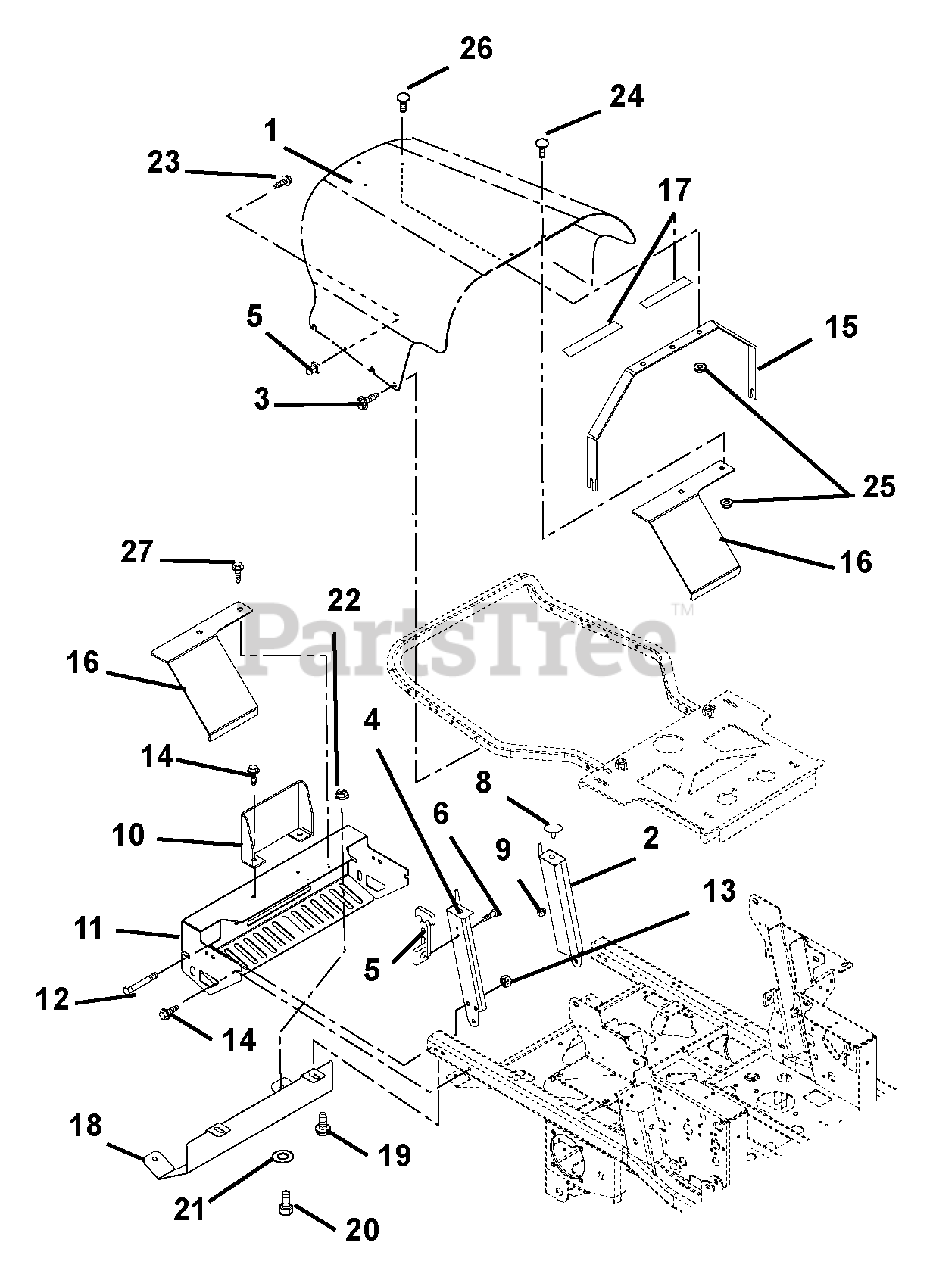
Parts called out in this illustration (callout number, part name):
1	Hood
2	Weldment, Hood Support, Left Hand
3	Screw, Tapping .38-16 x .50 Hex Washer Head
4	Weldment, Hood Support Right Hand
5	Latch, Rubber
6	Screw, Machine 10-24 x .50 Hex Washer Head
7	Screw, Machine 10-24 x 1.50 Hex Washer Head
8	Button Bumper
9	Nut-Spin Lock-Flange .312-18
10	Guard, Muffler
11	Bumper, Rear
12	Bolt, Hex .38-16 x 2.75 Grade 5
13	Nut-Locking-Top-Flange .38-16
14	Screw, Tapping .38-16 x .75 Hex Washer Head
15	Hood Support
16	Guard
17	VHB Tape 4941F
18	Heat Shield
19	Screw-Tapping .38-16 x .50 Hex Washer Head Thread Rolling YWZ
20	Bolt-Hex .38-16 x .75 Grade 5
21	Washer-Flat-Steel .438 x1.00X.083 YWZ
22	Nut-Locking-Top-Flange .38-16
23	Screw-Machine 10-24 x 1.50 Hex Washer Head
24	Bolt, Round Head Square Neck .25-20 x .50 Grade 5
25	Nut, Locking Top Flange .25-20
26	Bolt, Round Head Square Neck .25-20 x .75 Grade 5
27	Screw, Tapping .25-20 x .50 Hex Washer Head Thread
